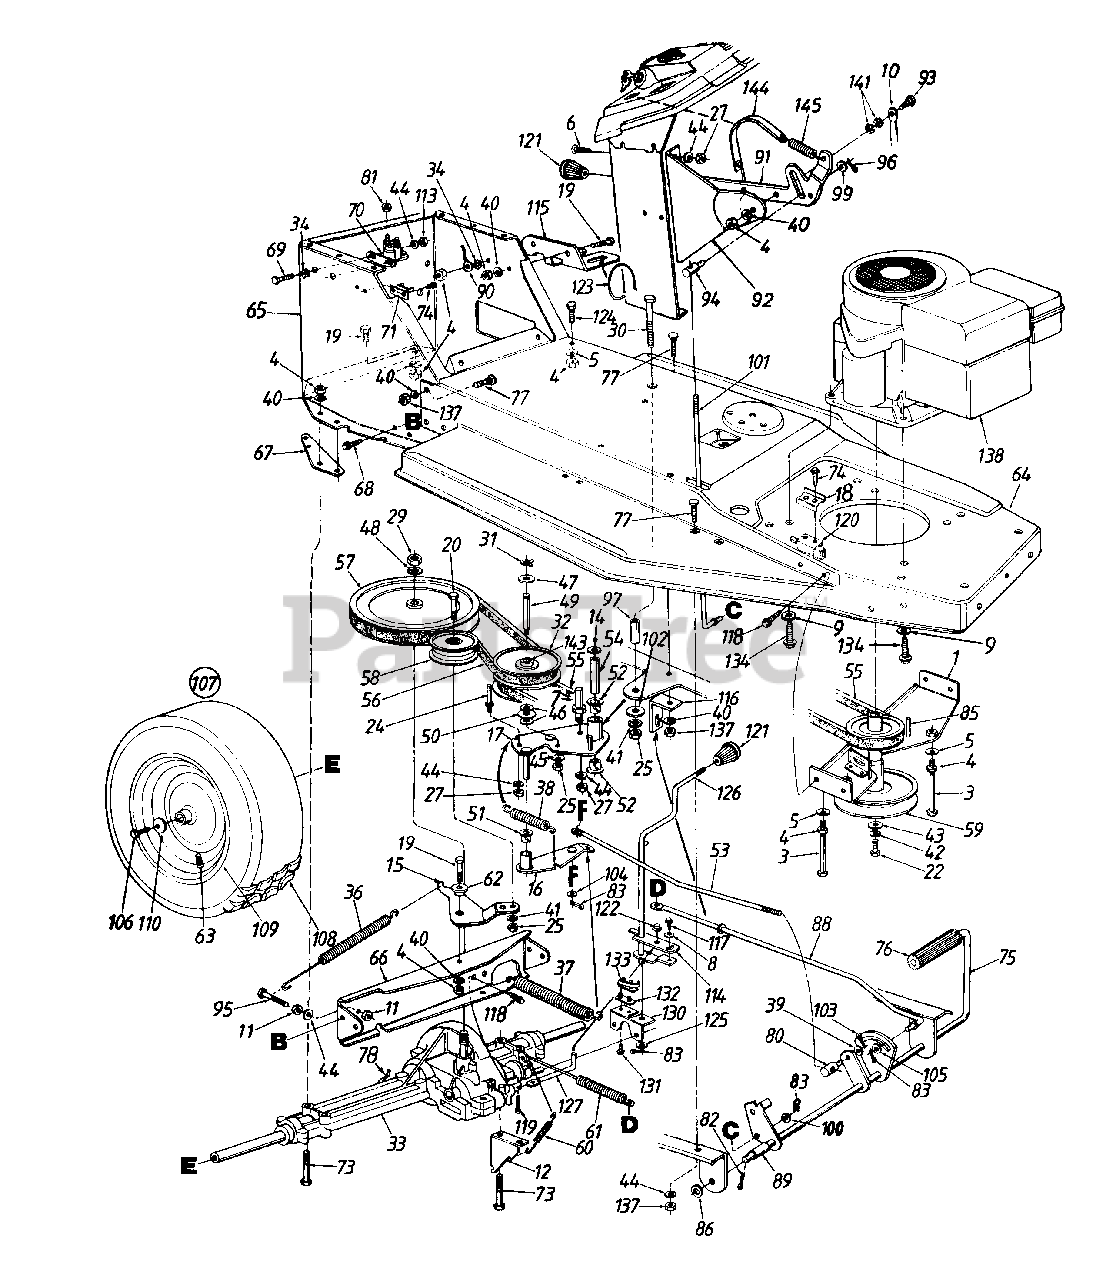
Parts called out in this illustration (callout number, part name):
1	Engine Pulley Belt Guard Ass'y.
3	Hex Bolt 5/16-18 x 5-1/2" Lg.
4	Hex Nut 5/16-18 Thd.
5	Bell-Wash..345" I.D. x .88
6	Truss-Mach. Scr. 1/4-20 x .50"
7	Belt Guard Pin 1/4-20 Thd.
8	Bell-Wash..265" I.D. x .75
9	Fl-Wash. 3/8" I.D. x .97" O.D.
10	Speed Selector Brace
11	Hex Nut 1/4-28 Thd.
12	Spring Retainer Brkt.
14	Fl-Wash. 3/8" I.D. x 1.26" O.D.
15	Idler Bracket
16	Var. Speed Torque Brkt. Ass'y.
17	Variable Speed Brkt. Ass'y.
18	Switch Plate
19	Hex Bolt 5/16-18 x .75" Lg.
20	Hex Bolt 3/8-24 x 2.0" Lg. Gr. 5
22	Hex Bolt 7/16-20 x 1.5" Lg.
24	Belt Guard Pin
25	Hex Nut 3/8-24 Thd.
27	Hex Nut 1/4-20 Thd.
29	Hex Jam Nut 9/16-18 Thd.
30	Hex Bolt 3/8-24 x 3.75" Lg.
31	Snap Ring
32	Variable Speed Pulley Ass'y.
33	Transaxle Ass'y. Comp.
34	Ext. L-Wash. 5/16" I.D.
36	Extension Spring 6.12" Lg.
37	Extension Spring 6.74" Lg.
38	Extension Spring 2.59" Lg.
39	Fl-Wash..385" I.D. x .620"
40	L-Wash. 5/16" I.D.
41	L-Wash. 3/8" I.D.
42	L-Wash. 7/16" I.D.
43	Fl-Wash..450" I.D. x 1.25"
44	L-Wash. 1/4" I.D.
45	Bell-Wash..39" I.D. x 1.13"
46	Fl-Wash..56" I.D. x 1.0" O.D.
47	Washer "Teflon" .565 I.D.
48	Bell-Wash. 9/16" I.D. x 1.125" O.D.
49	Shaft .56" Dia. x 3.875" Lg.
50	Thrust Brg. 1.25 O.D.
51	Flanged Nyliner Brg.
52	Nyliner Flanged Brg.
53	Speed Control Rod
54	Spacer
55	V-Belt
56	V-Belt
57	V-Pulley 8" Dia.
58	Idler Pulley 3-1/8" Dia.
59	Dbl. Pulley 6.0" Dia. x 3.56"
60	Extension Spring 3.18" Lg.
61	Extension Spring 7.08" Lg.
62	Shld. Spacer .500" Dia.
63	Air Valve
67	Transaxle Brkt. Reinforcement
68	Hex Wash. AB-Tap Scr. 5/16 x .75" Lg.
69	Hex Bolt 1/4-20 x .62" Lg.
70	Solenoid
71	Circuit Breaker
73	Hex Bolt 5/16-18 x 2.75" Lg.
74	Truss Mach. B-Tap Scr. #10 x .50" Lg.
77	Ribbed Neck Bolt 5/16-24 x .84"
78	Spring Anchor
80	Ferrule
81	Hex Sems Nut 1/4-20 Thd.
82	Cot-Pin 1/8" Dia. x 1.25" Lg.
83	Cot-Pin 3/32" Dia. x .75" Lg.
85	Sq. Key 1/4 x 2.0" Lg.
86	Fl-Wash..635" I.D. x 1.0"
88	Brake Rod
89	Spacer 5/8" I.D. x 1.2" Lg.
90	Ground Wire 7.25" Lg.
91	Speed Selector Lever
92	7 Speed Selector Brkt.
93	Shld. Bolt .437" Dia. x .47" Lg.
94	Ferrule
95	Hex Bolt 1/4-28 x 1.25" Lg.
96	Intern. Cot-Pin 5/16" Dia.
97	Spacer .375" I.D. x .625"
99	Fl-Wash..344" I.D. x .62"
100	Fl-Wash..25" I.D. x .62" O.D.
101	Speed Control Rod
102	Fl-Wash. 3/8" I.D. x 1.25" O.D.
103	Cot-Pin 1/8" Dia. x 1.0" Lg.
104	Fl-Wash..34" I.D. x .68"
105	Fl-Wash..34" I.D.
106	Hex L-Bolt 5/16-24 x .75" Lg.
110	Bell-Wash..345" I.D. x .88"
113	Hex Jam Nut 1/4-20 Thd.
114	Shift Lever Adjusting Link
115	Shift Lever Spring Brkt.
118	Hex Wash. Hd. Tap Scr. 1/4-20 x .5" Lg.
119	Intern. Cotter Pin
120	Safety Switch (Clutch)
122	Retaining Ring
123	Compression Spring 1.5" Lg.
124	Hex Wash. Hd. Scr. 5/16-18 x 7/8" Lg.
125	Fl-Wash..469" I.D. x .88"
130	Shift Lever Support
131	Hex Wash. Hd. #8 x .50" Lg.
132	Insulator Nut Plate
133	Spring Switch
134	Hex Tap Scr. 3/8-16 x 1.25"
137	Hex Nut 5/16-24 Thd.
138	Engine
141	Wave Wash..445" I.D.
143	Needle Brg.
144	7-Speed Indicator Strip
144	Speed Indicator Hook
145	Ext. Spring 2.04" Lg. (Style 0, 1)
145	Muffler
